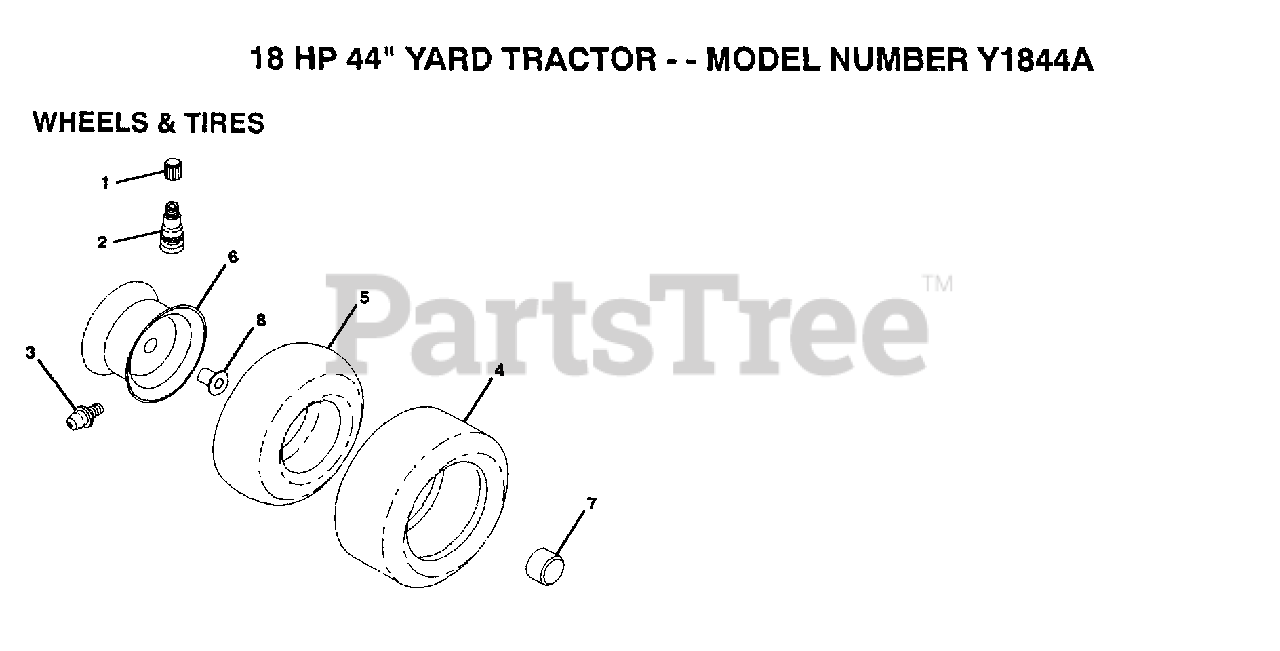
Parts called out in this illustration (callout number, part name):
1	VALVE CAP
2	VALVE STEM LT
3	FITTING LT
5	TUBE.23X8/10-12
5	TUBE.5.3/4.5/6
7	HUB CAP
8	"FLANGE, BEARING"
